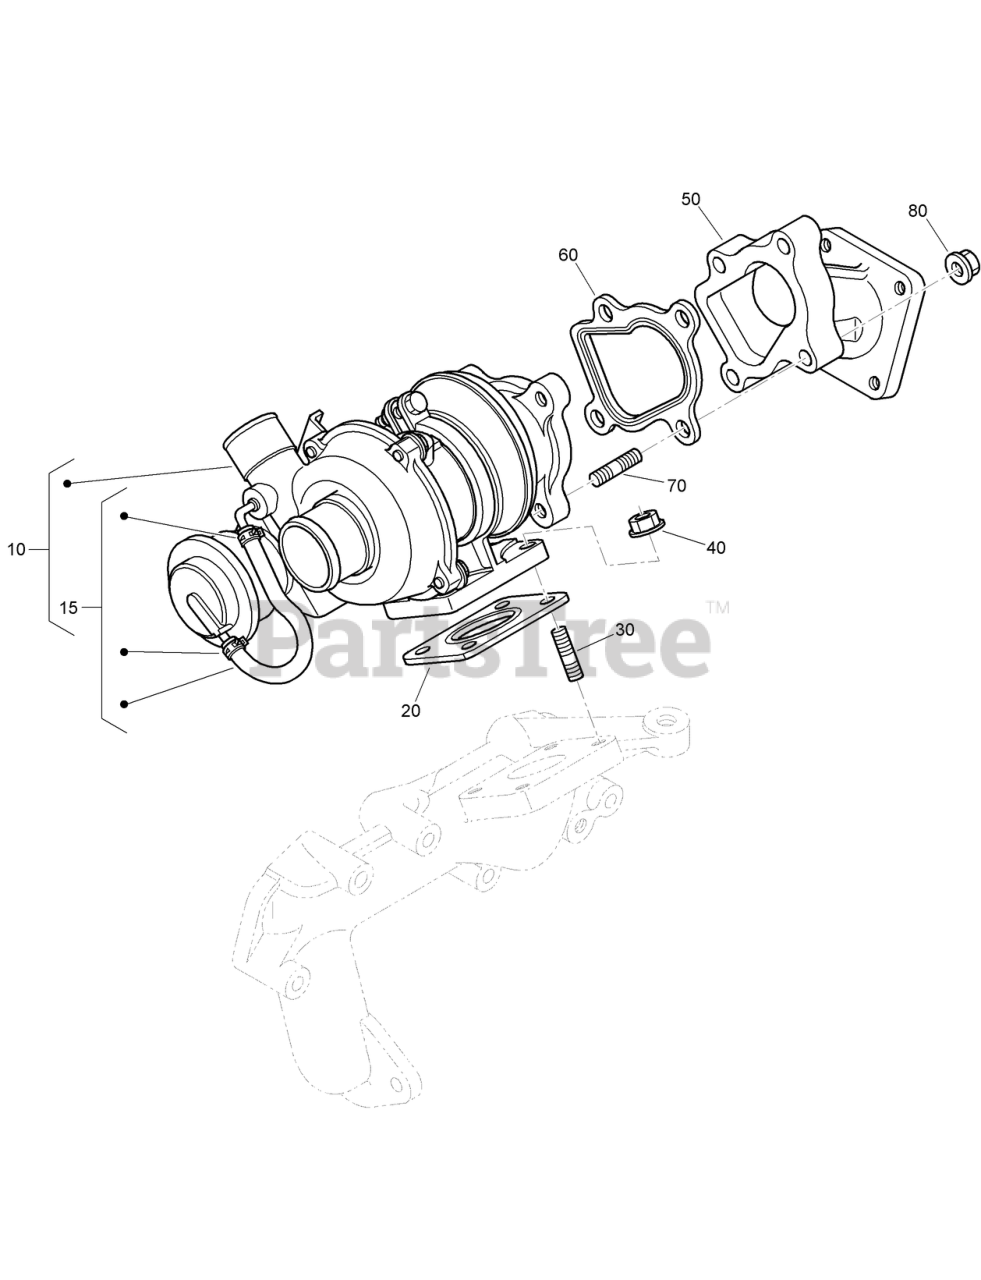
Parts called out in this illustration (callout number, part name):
10	TURBO CHARGER ASM
15	HOSE ASM
20	GASKET
30	BOLT-STUD
40	NUT-FLANGE
50	FLANGE-MUFFLER
60	GASKET-FLANGE, MUFFLER
80	NUT-FLANGE
